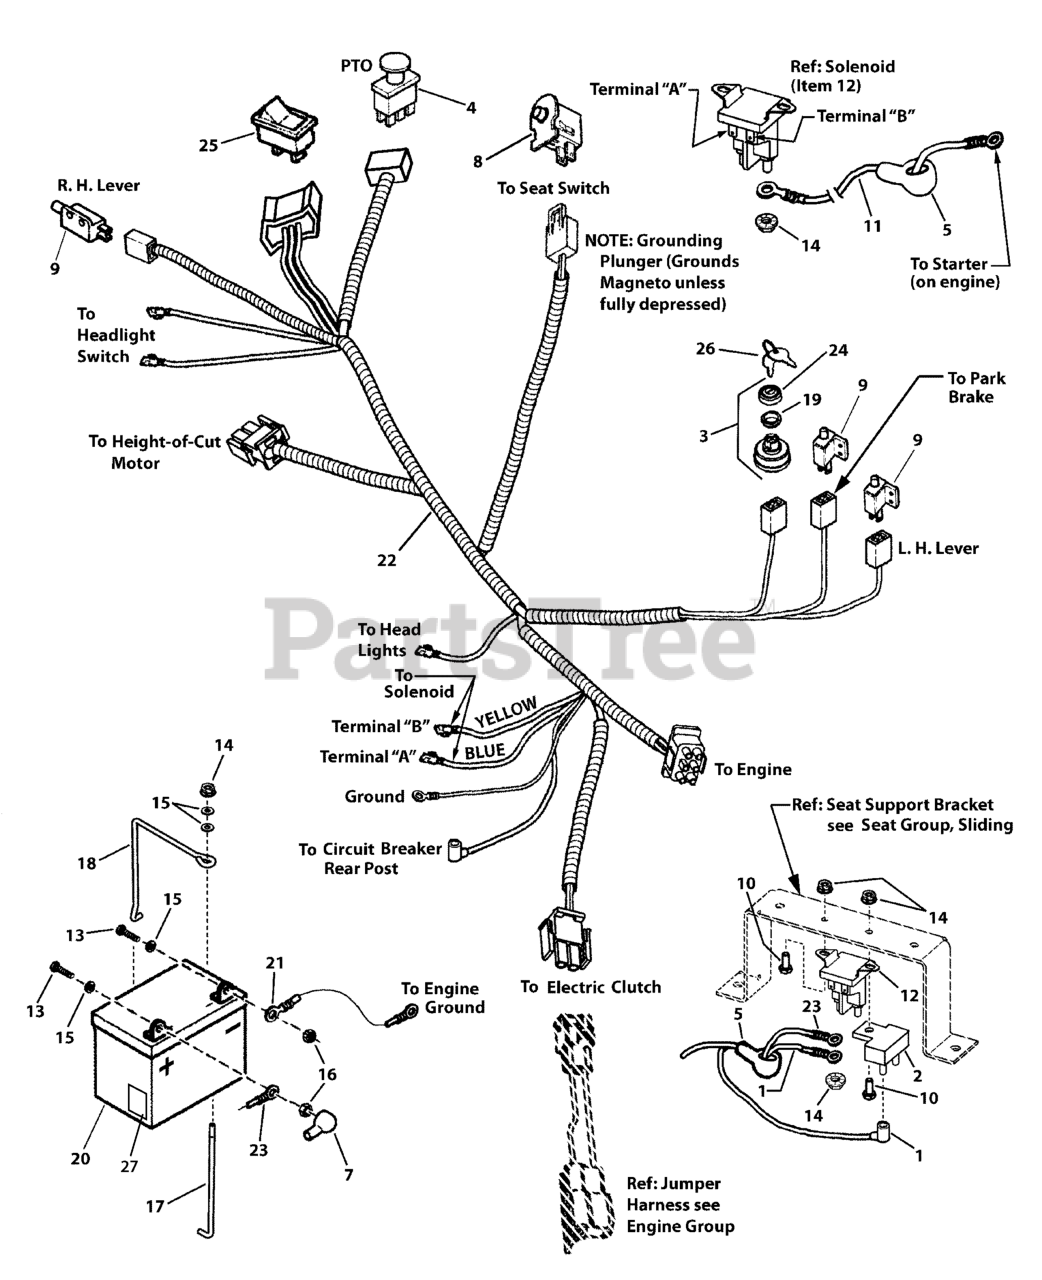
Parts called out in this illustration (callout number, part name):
1	WIRE, 12 Gage, 8", Red
2	BREAKER, Circuit 12 Volt 20 AMP w/Tab
3	SWITCH ASSEMBLY, Ignition, 5/8-32 6 Pin Indak
4	SWITCH, PTO, Push/Pull
5	COVER, Terminal, Red Vinyl
7	COVER, Battery Cable, Red
8	SWITCH, Seat, Push Button (NC)
9	SWITCH, DPDT (NC/NO)
10	SCREW, 1/4-20 x 5/8" Hex Head Cap, GR 5
11	CABLE, Starter, 8 Gage, 14", Black
12	SOLENOID, Super Trombetta - 2 Terminal
13	SCREW, 1/4-20 x 5/8" Hex Head Cap, GR 5 or B
14	NUT, 1/4-20 Hex Nyloc
15	WASHER, 1/4" Flat
16	NUT, 1/4-20 Hex Flange Lock, YZ
17	HOLD DOWN, Battery
18	BRACKET, Battery
19	NUT, 5/8"-32 E-Start
20	BATTERY, 12 Volt, 230 CCA
21	CABLE, Battery Negative, 8 Gage, 20", Black
22	HARNESS, Wiring, ZT
23	CABLE, Battery Positive, 8 Gage, 18", Red
24	CAP, Ignition Switch
25	SWITCH, Rocker Electric Height-Of-Cut
26	KEYS, Blister Pk (KIDS+MWRS DON'T MIX) English/Spanish
27	DECAL, Die Hard
